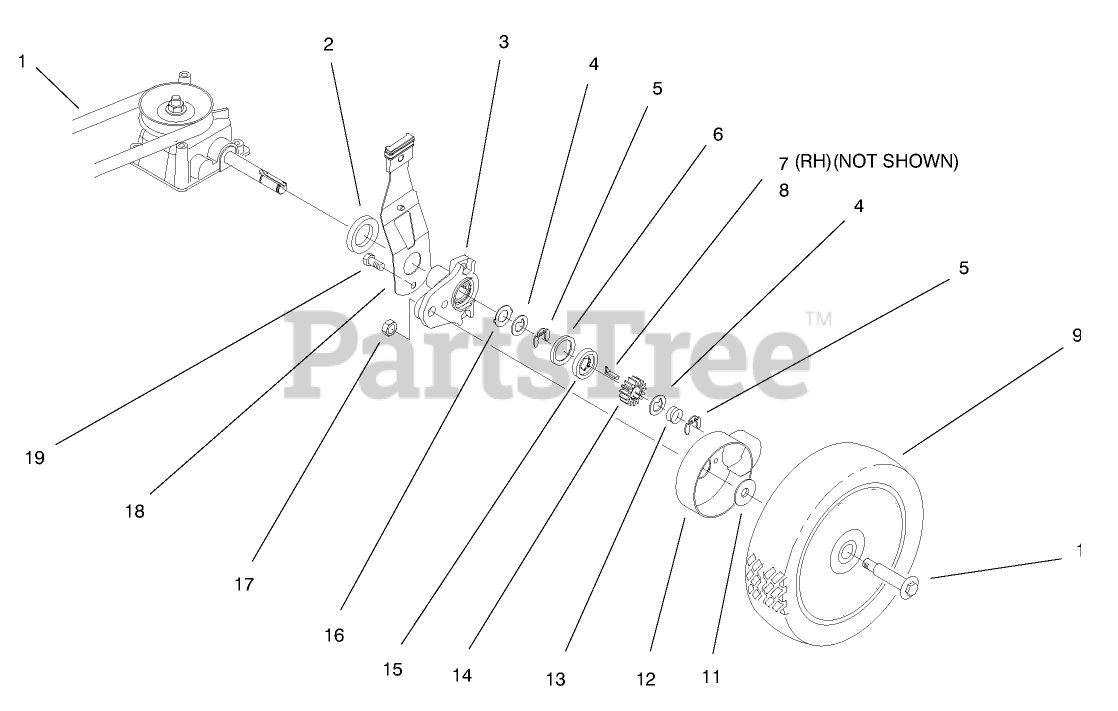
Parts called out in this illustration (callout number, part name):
1	V-BELT
2	SPACER-SHAFT, AXLE
3	REAR HEIGHT ADJUSTMENT ARM ASM
4	WASHER-THRUST, KEYED
5	RING-RETAINING,CLIP
6	RING-FRICTION
7	KEY-ROCKING, RH
8	KEY-ROCKING, LH
9	WHEEL ASM
10	BOLT-SHOULDER
11	WASHER-STEPPED
12	COVER-WHEEL
13	SPRING-COMPRESSION
14	GEAR-PINION
15	WASHER-CLUTCH
16	WASHER-ARM, PIVOT
17	NUT-JAM, LOCKING
18	REAR SPRING ARM ASM
19	SCREW-HWH
